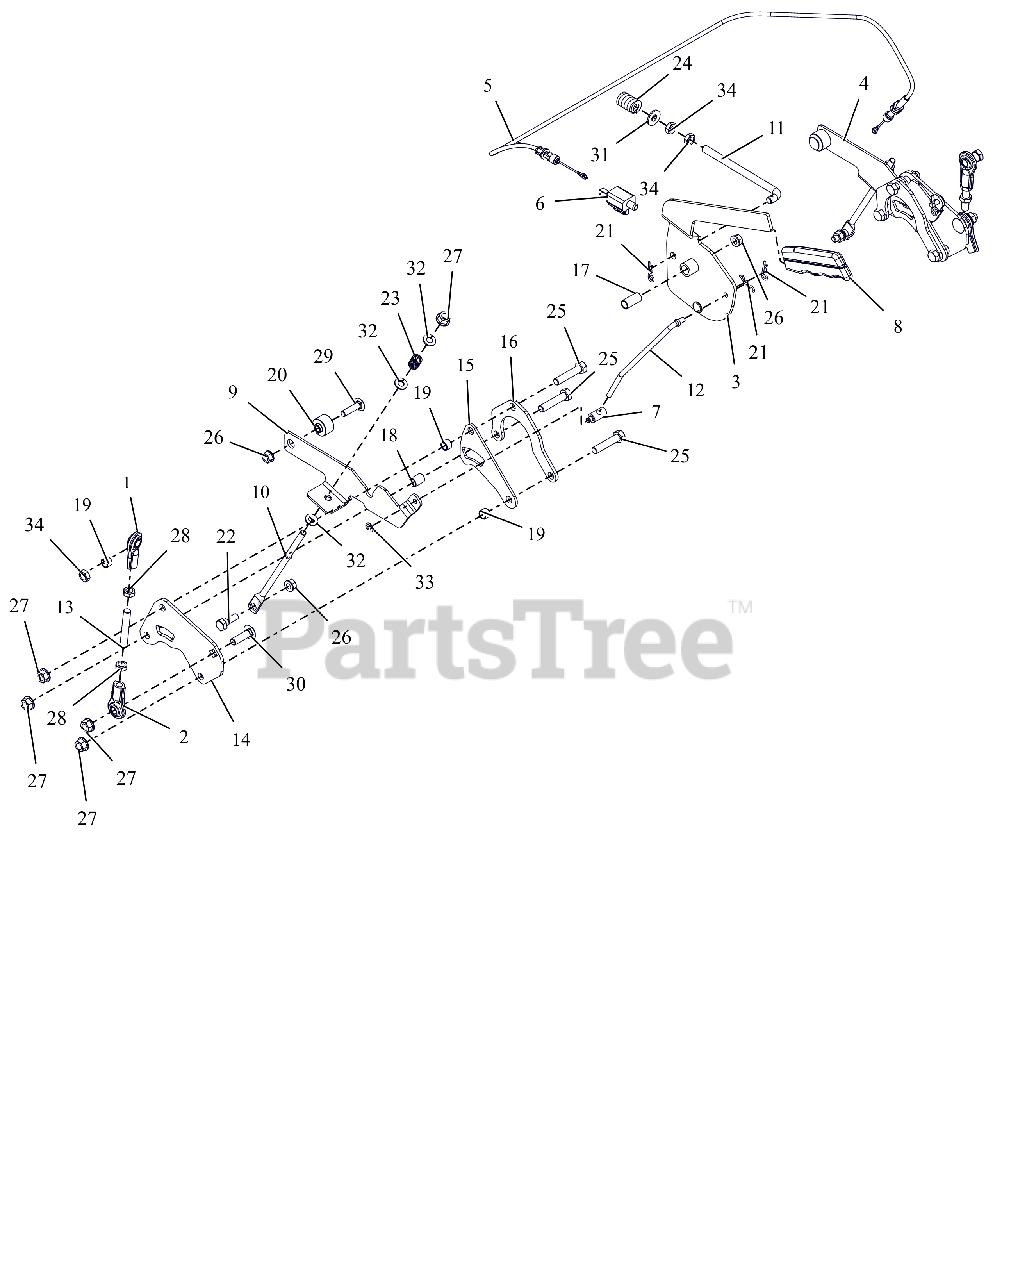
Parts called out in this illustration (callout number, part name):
1	ROD END, .38 RH
2	END, ROD-.38 LH
3	LEVER, PARKING BRAKE
4	ARM, BRAKE - LH (W/PIN)
5	CABLE, BRAKE
6	SWITCH, SINGLE POLE N.O.
7	TRUNION, 1/4-20
8	GRIP, PARKING BRAKE (YELLOW)
9	ARM, BRAKE-RH
10	ROD, LINK - TRANSMISSION BRAKE
11	ROD, OVER CENTER
12	ROD, BRAKE LINK
13	ROD, STEERING LINK
14	BRKT, TRANSAXLE STEERING
15	BRKT-SPACER
16	PLATE, REAR REINFORCING
17	BSHG-SLV .385X.500X1.045
18	SPCR, SLV .385X.500X.652
19	SPCR, SLV .385X.500X.350
20	SPCR, FLANGE
21	PIN, HAIR #213 .08X1.19 ZCC
22	BOLT,SHLDR .38X.25 -.31-18X.75
23	SPRING, COMPRESSION
24	SG-COMP .187X.56X1.62
25	BLT, HEX .38-16X1.75 G5 ZCC
26	NUT-LK-TOP-FLG .312-18 GF ZCC
27	NUT-LK-TOP-FLG .38-16 ZC120
28	NUT, HEX-JAM .38-24 ZCC
29	BLT, RHSSN.31-18X1.25 G5 ZCC
30	BLT,RHSSN .38-16X1.25 G5 ZCC
31	WSHR,FLT .375X.875X.083 ZCC
32	WSHR,FLT .344X.688X.065 ZCC
33	RG-RTNG-EXT .250X.025
34	NUT,HEX .50-13 G2 ZCC
